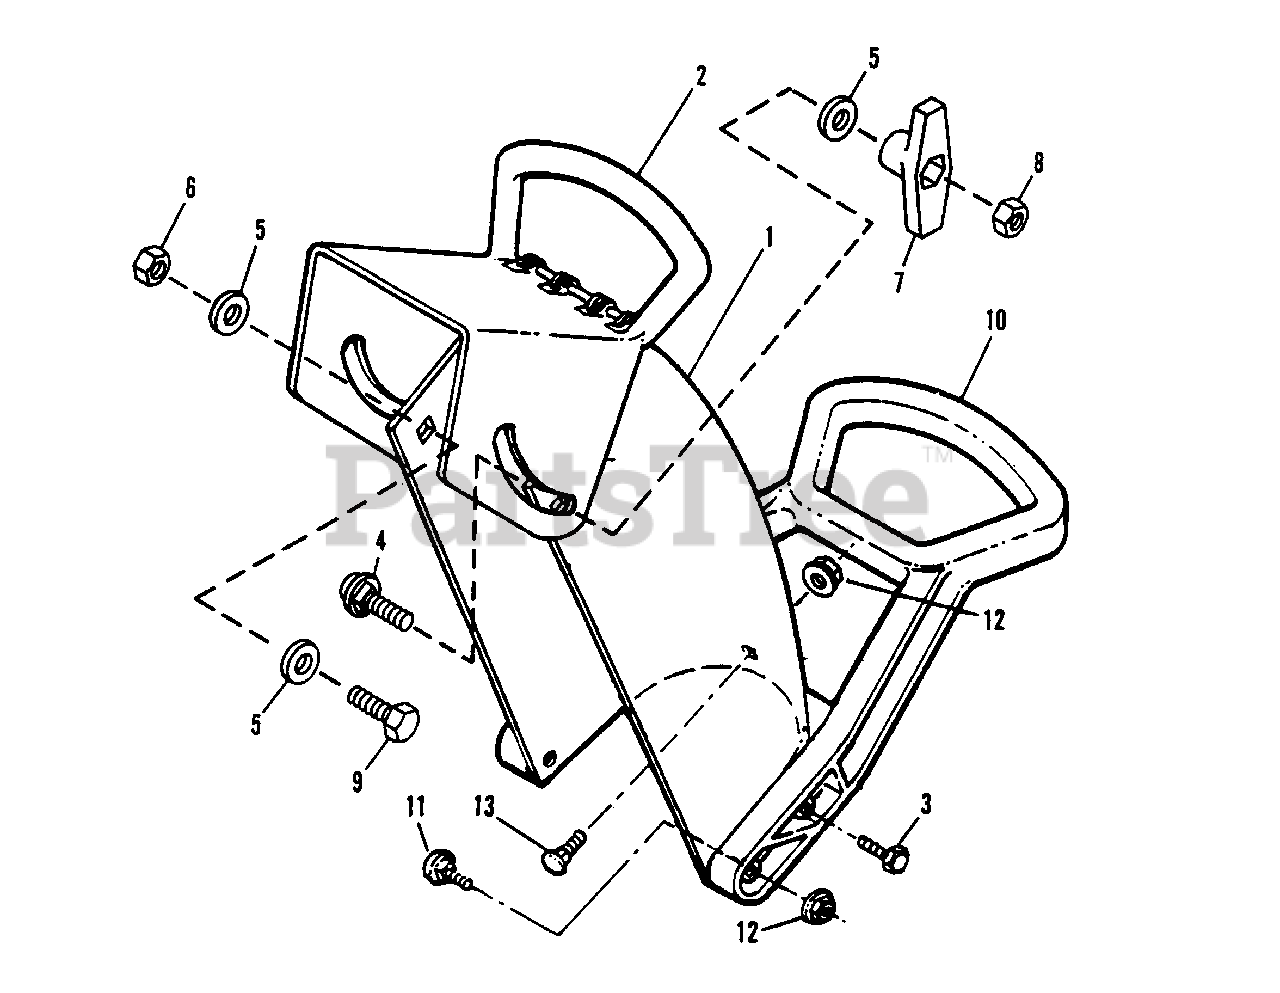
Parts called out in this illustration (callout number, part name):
1	CHUTE, Discharge
2	DEFLECTOR, Chute
3	SCREW, 5/16-18 x 3/4" Hex Cap
4	BOLT, 5/16-18 x 1" Short Neck Carriage (Gr. 5)
5	WASHER, 5/16 Flat
6	NUT, 5/16-24 Hex Center Lock
7	T-KNOB, Plastic
8	NUT, 5/16-18 Hex
9	SCREW, 5/16-24 x 3/4" Hex Cap
10	HANDLE, Chute Control
11	BOLT, 5/16-18 x 1-1/4" Short Neck Carriage (Gr. 5)
12	NUT, 5/16-18 Hex Flange Lock, Grade 5
13	BOLT, 5/16-18 x 3/4" Short Neck Carriage
